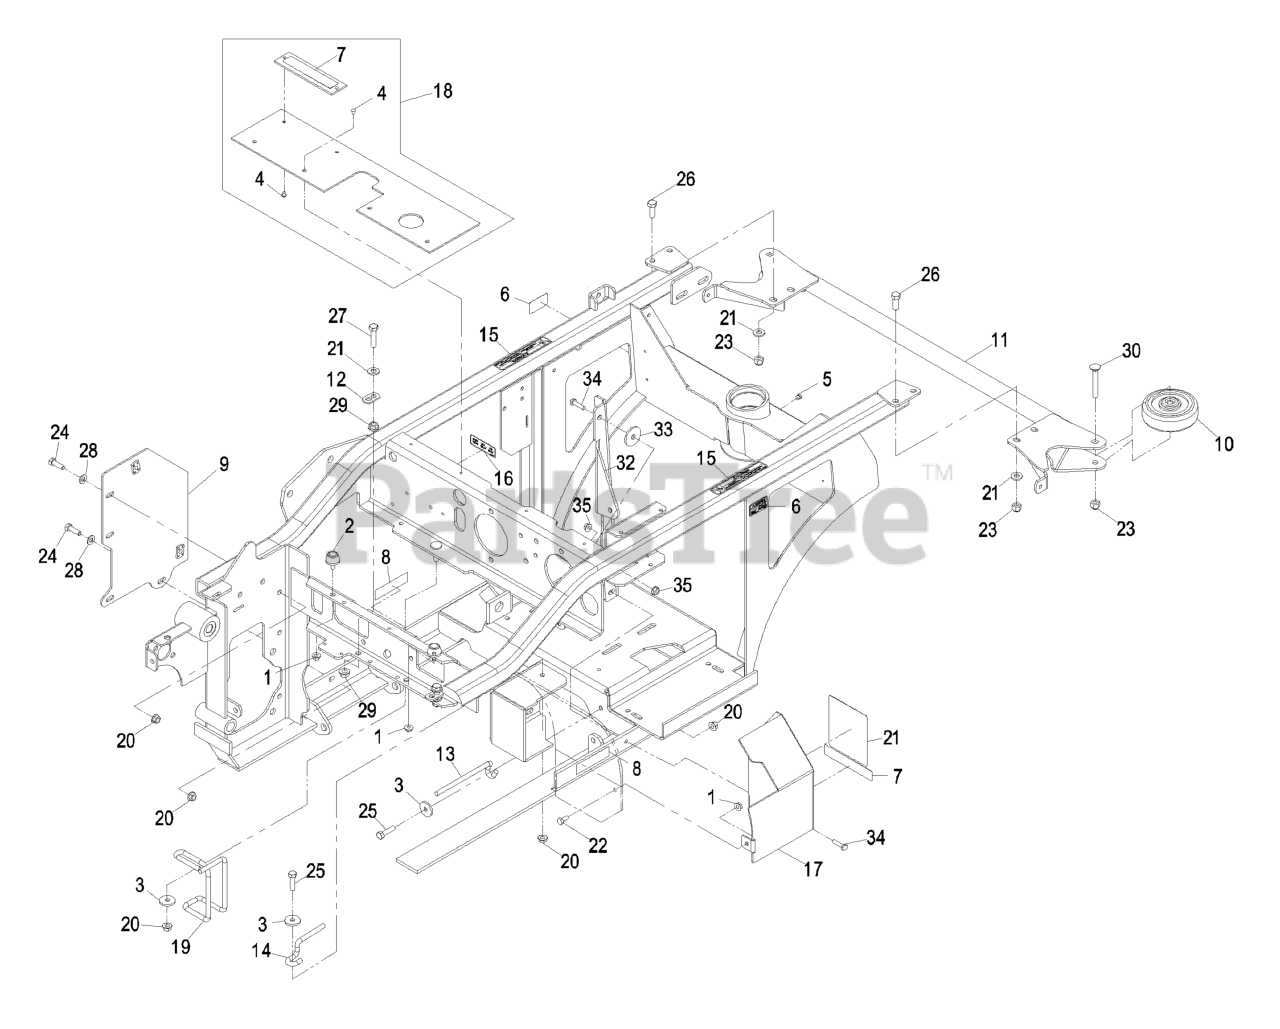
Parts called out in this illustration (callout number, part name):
2	BUMPER-RUBBER
4	RIVET-POP
6	DECAL-SURFACE, HOT
7	DECAL-WARNING
8	DECAL-COVER, MISSING
9	WLD,FENDER (RAW)
10	ROLLER-BUMPER
11	BUMPER-REAR
12	TAB,SPRING ANCHOR
13	GUIDE-BELT
14	GUIDE-BELT
15	DECAL,PINCH POINT
16	DECAL,RELAY
18	LIFT SHIELD ASM
19	GUIDE,BELT (PLATED)
21	DECAL,BELT ROUTING
22	SCREW-HH
23	NUT-LOCK, NI
24	SCREW-HH
25	SCREW-HH
26	SCREW-HH
27	SCREW-HH
28	WASHER-PLAIN
29	NUT-HHF, WHIZ
30	SCREW-CARR
31	WASHER-FLAT
32	BRACE-PTO
34	SCREW-HH
